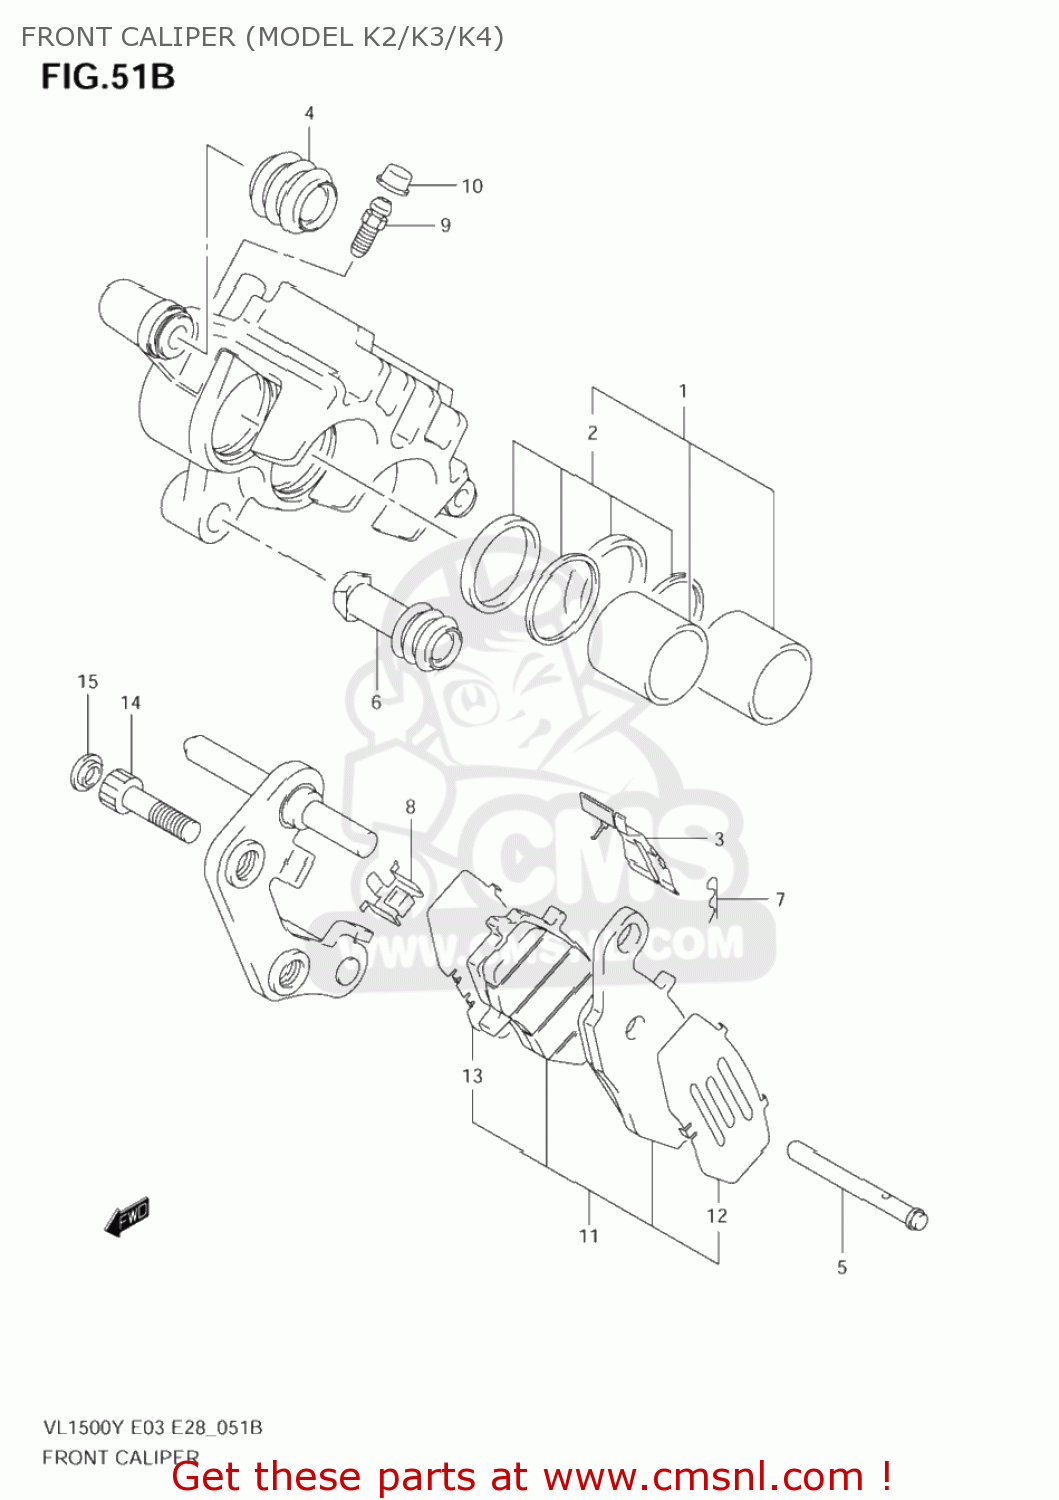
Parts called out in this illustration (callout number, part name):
1	PISTON SET
2	SEAL SET,PISTON
3	SPRING,PAD,R
4	BOOT,AXLE
5	PIN,PAD
6	INSULATOR,AXLE
7	CLIP,PAD PIN
8	GUIDE,PAD
9	BLEEDER
10	CAP,BLEEDER PLUG
11	PAD & SHIM SET (NAS)
12	SHIM,PAD
13	SHIM,PAD NO.2
14	BOLT(10X33)
15	CAP(OD:12)
